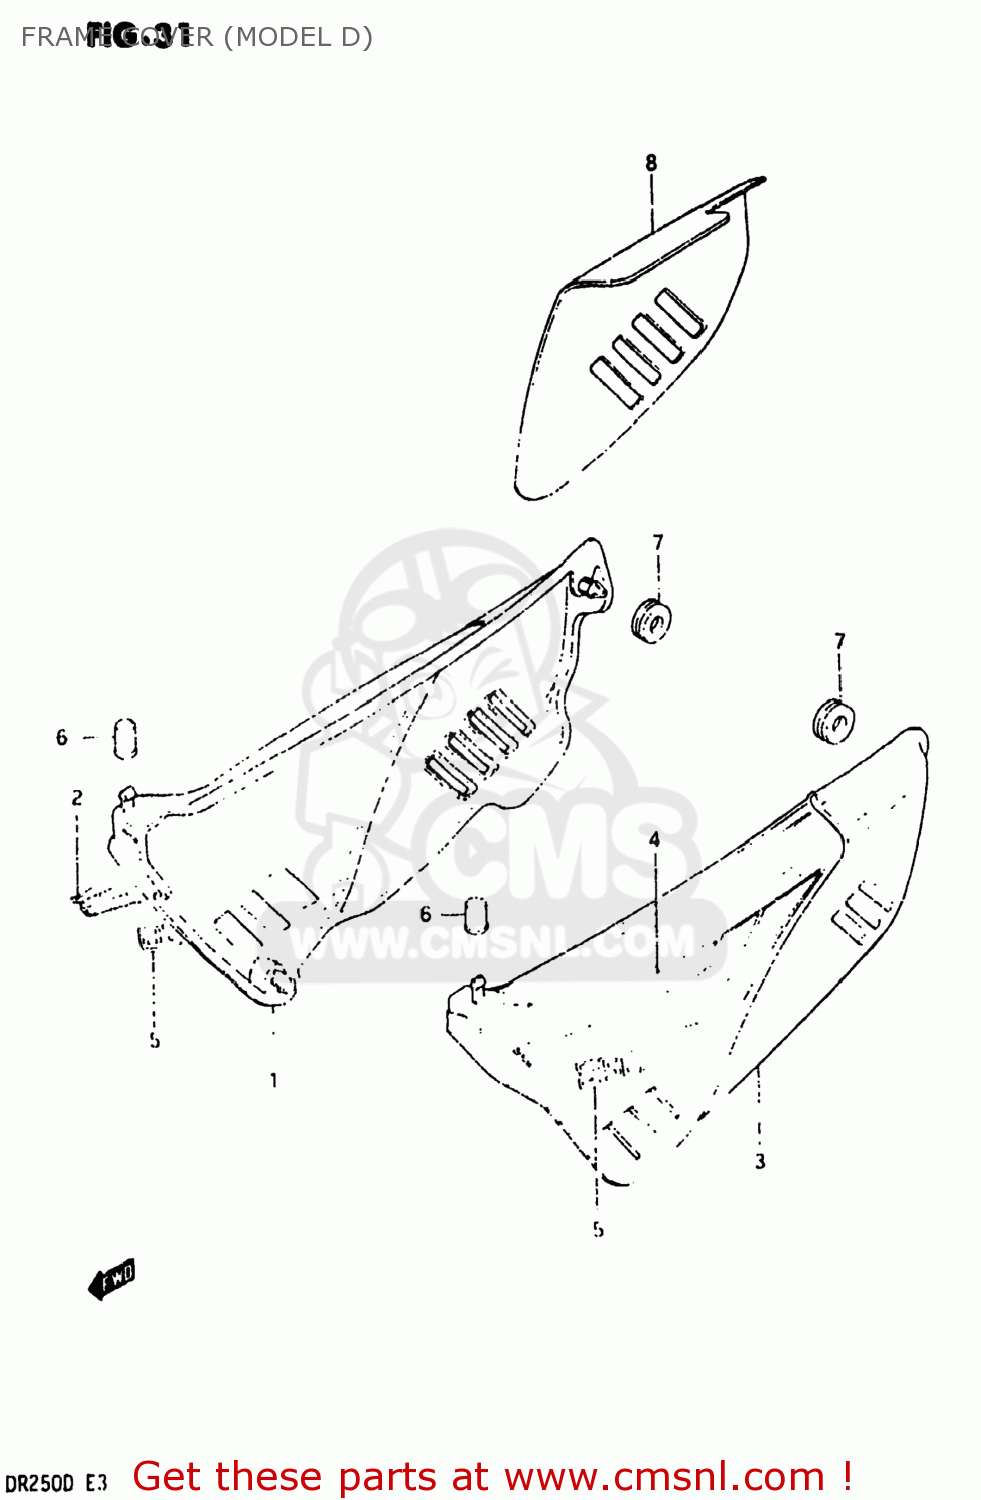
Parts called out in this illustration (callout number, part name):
1	COVER,FRAME,RIGHT
2	TAPE,FRAME COVER,RIGHT
3	COVER,FRAME,LEFT
4	TAPE,FRAME COVER,LEFT
5	EMBLEM
6	CUSHION
7	CUSHION
8	HEAT SHIELD,FRAME COVER
